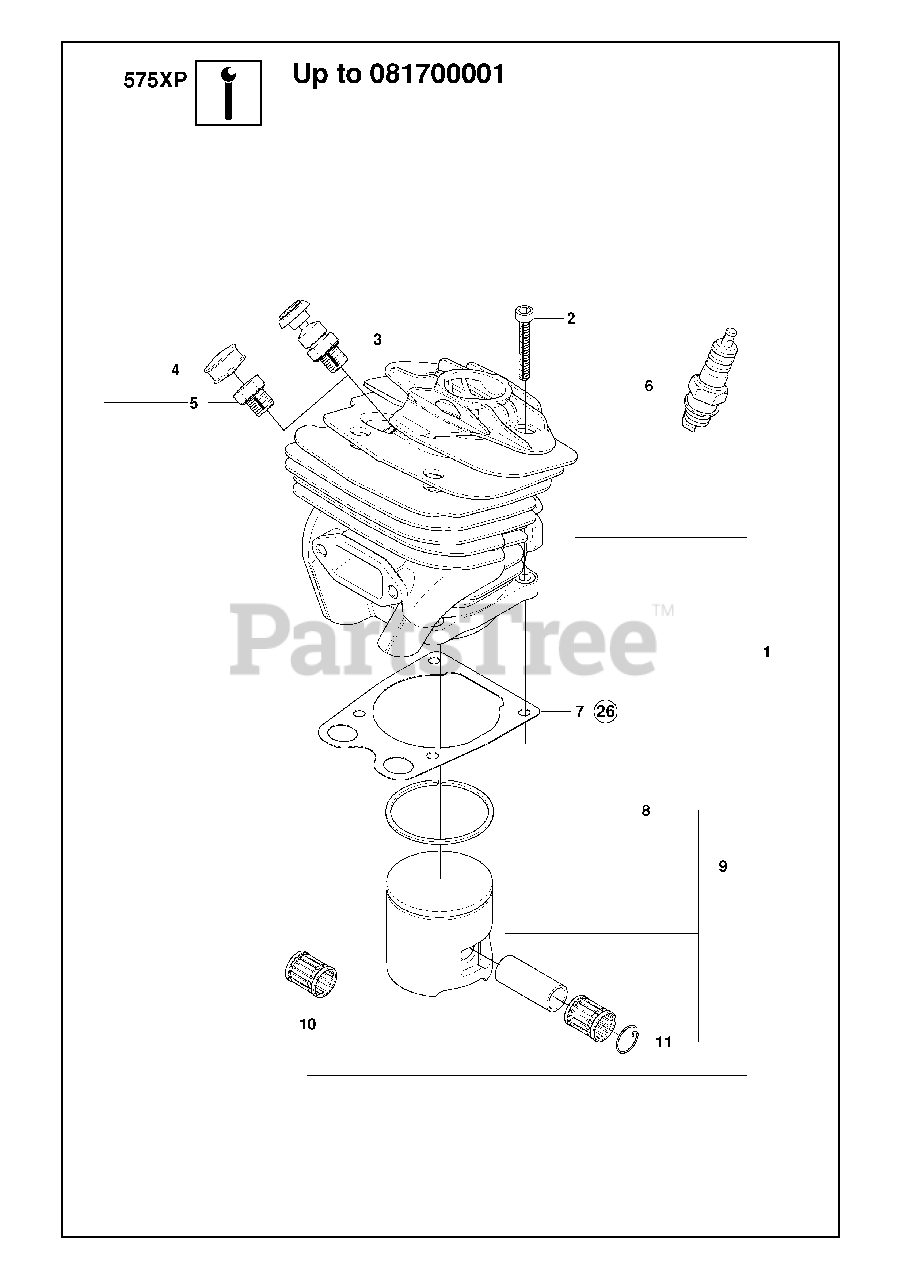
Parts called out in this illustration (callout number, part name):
1	%CYLINDER
2	SCREW MC6S 5X25
3	VALVE
5	CYLINDER PLUG
6	BPMR7A NGK SPARK PLUG
8	PISTON RING
9	PISTON 49 MM
10	SUPPORT BUSHING
11	WRIST PIN CLIP
26	GASKET SET
